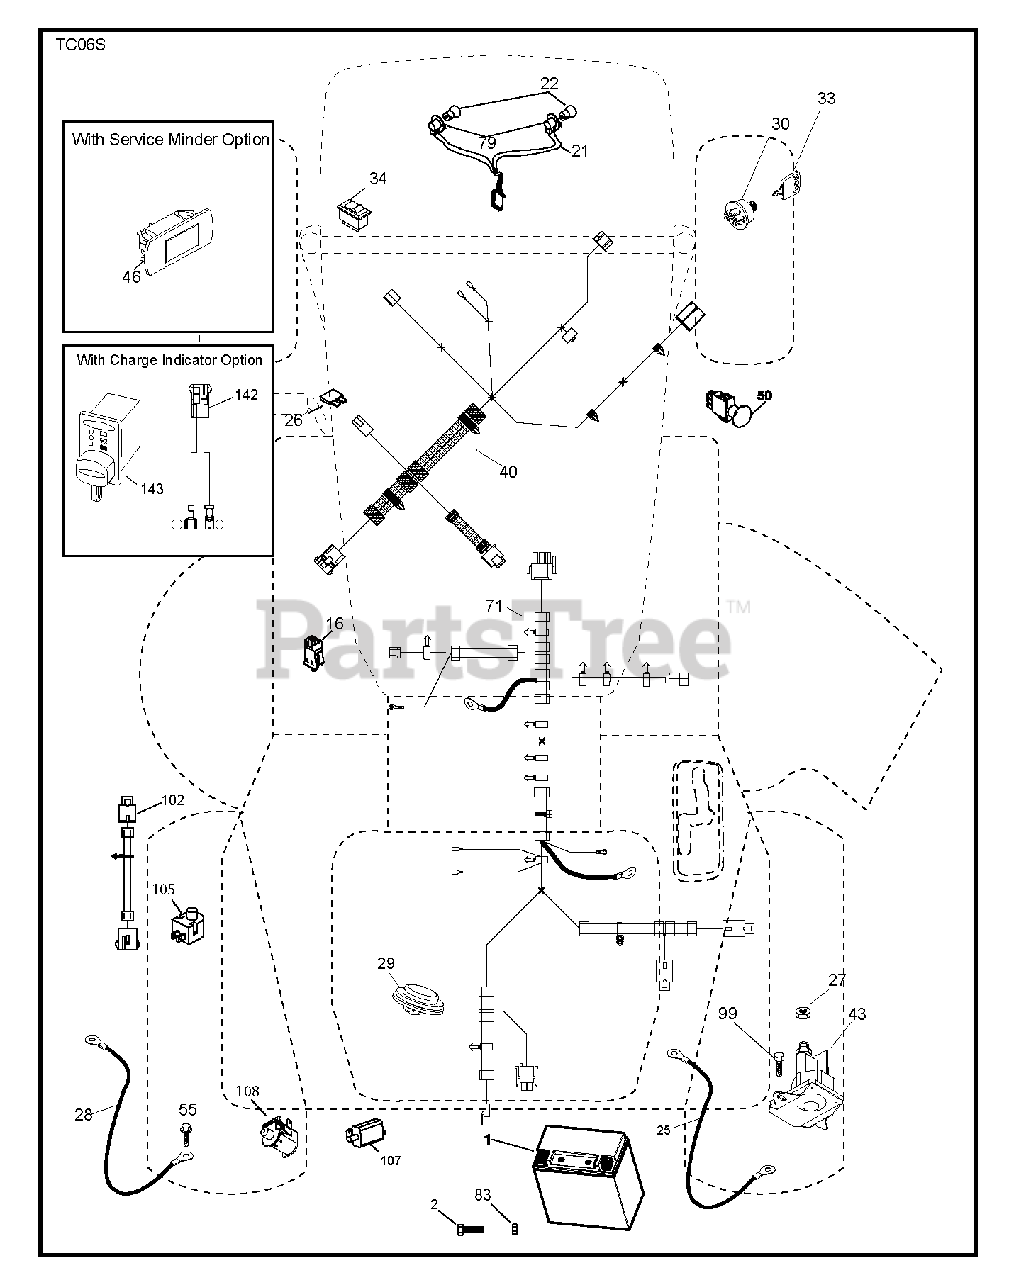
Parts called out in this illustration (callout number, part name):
1	BATTERY BATTERY 14AH 12V LEOC
2	SCREW.HEX.HEAD.CAP.M6 X1.12W
16	SWITCH INTERLOOK PUSH-IN
21	HARNESS.LIGHT W/4152J BULBS
25	CABLE CABLE.RED.20.8AWG.M6.CRD
26	FUSE 20AMP
27	NUT
28	CABLE CABLE.BLACK.20.8AWG.M6.C
29	SWITCH.SEAT.DELTA.OPC.
30	SWITCH.IGN.DELTA.W.LGH.ROS
33	KEY.CHAIN.BLISTER.PACK.GEN.USA
40	HARNESS.DASH.ELECT.SRD.BAT.CHR
43	SOLENOID.W/BRASS.PLUNGER
46	GUAGE.SRVCMNDR.HRMTR.
50	RB PTO.SWITCH.8 TERMINAL.BLACK
55	SCREW 5/16"
71	HARNESS
79	BULB HOLDER ASM.
83	NUT NUT SQUARE
99	SCREW
102	HARNESS ASSY
105	REVERSE SWITCH
107	.WITCH.FULL BAGGER.INDICATOR
108	SWITCH.SNAPMOUNT.NC
142	CHARGE.PORT.PIGTAIL HARNESS
143	CHARGE.PORT
